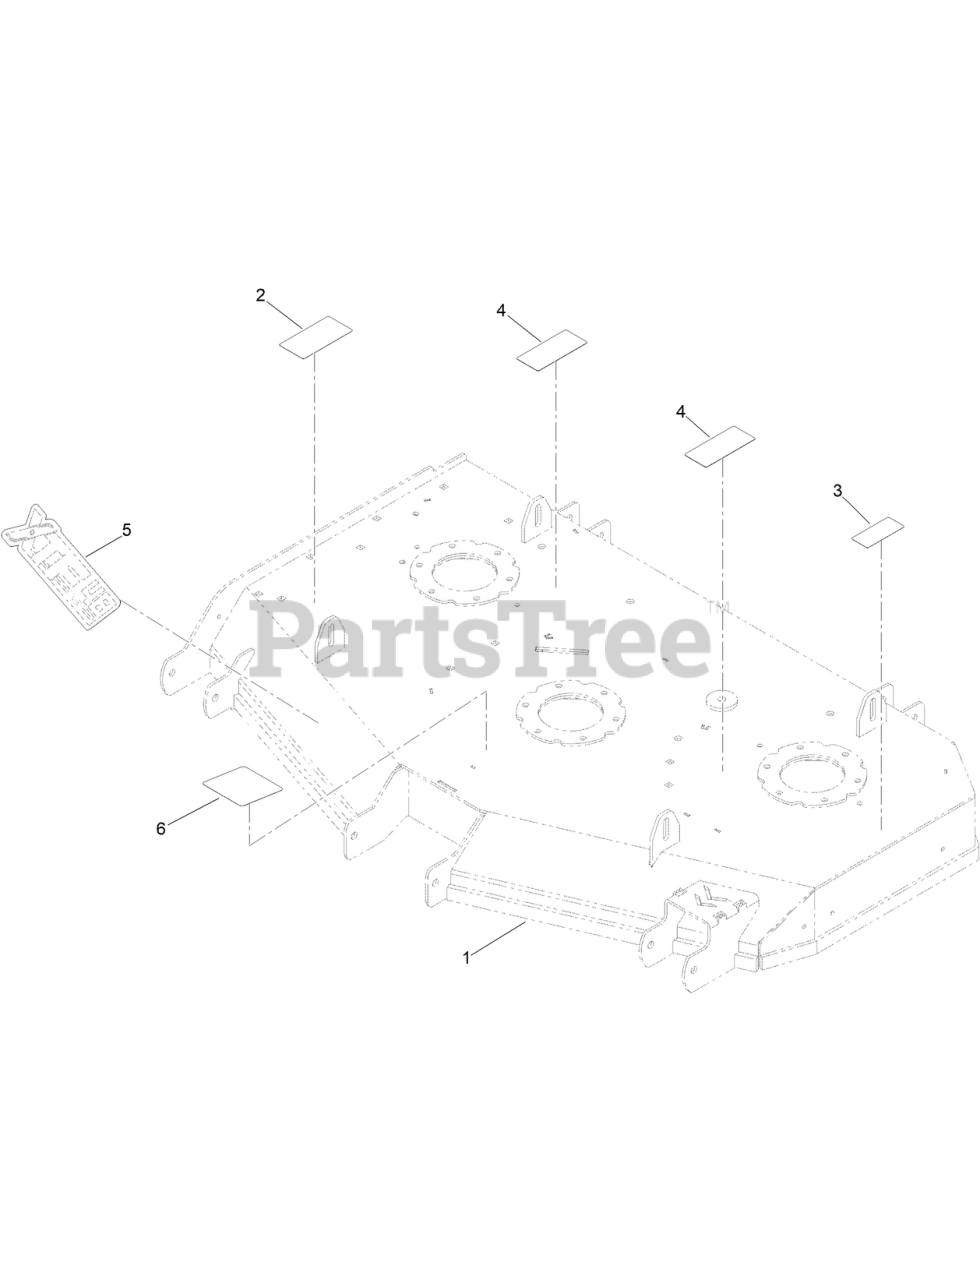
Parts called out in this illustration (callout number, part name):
2	DECAL-DANGER, DECK
3	DECAL-SAFETY BLADE TORQUE
4	DECAL-ROTATING FAN HAZARD
5	2020 XTF-48 DECAL
6	DECAL-DECK BELT ROUTING
